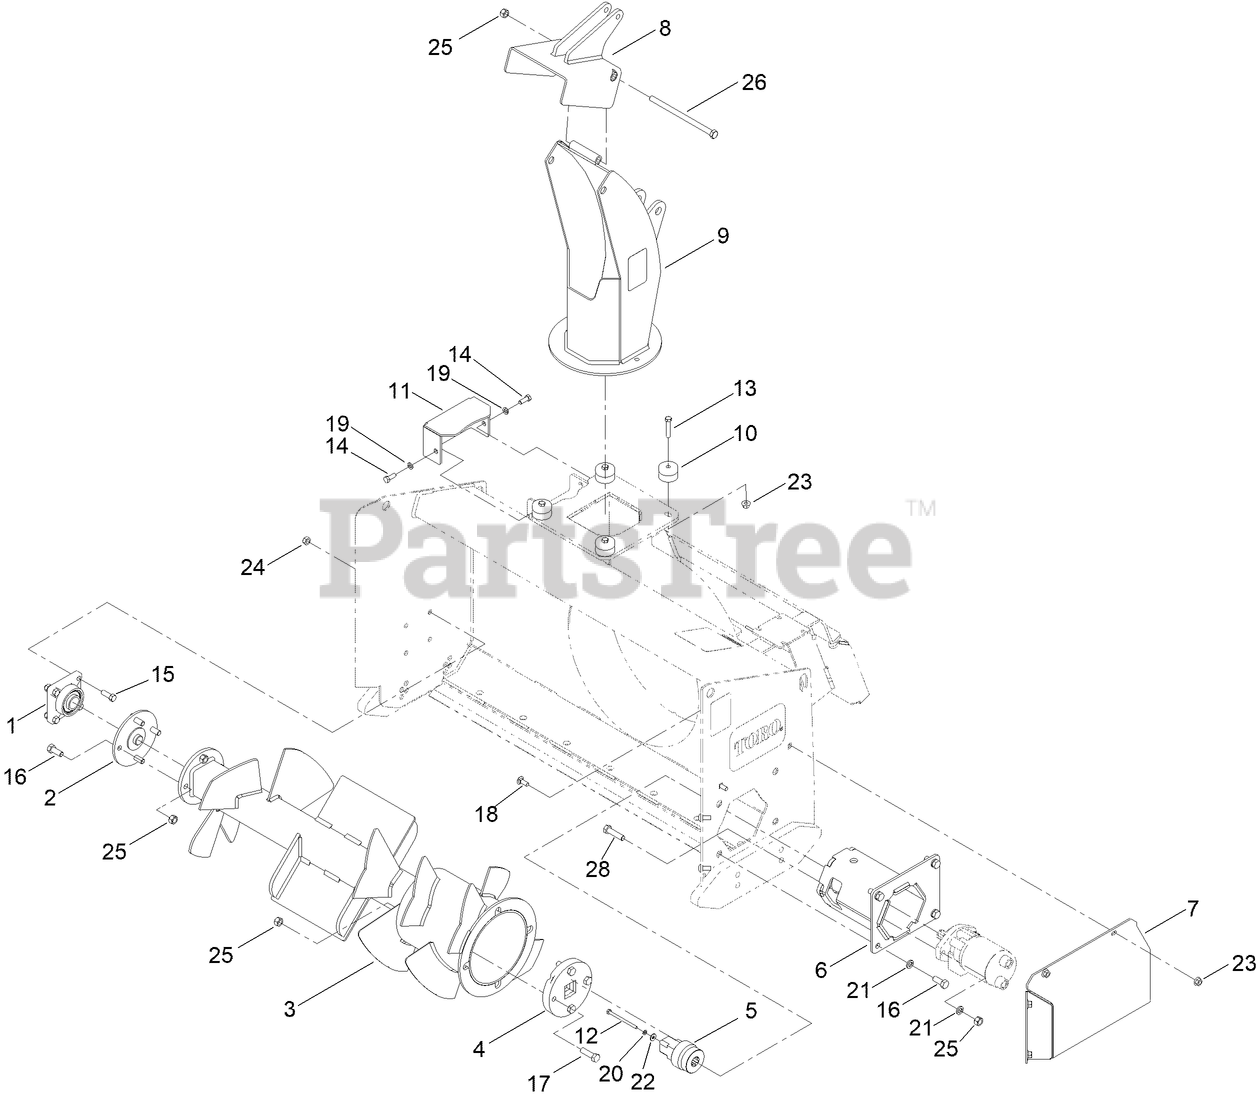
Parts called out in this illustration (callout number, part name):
1	BEARING
3	PADDLE ASM
4	COUPLER-PADDLE/MOTOR
5	ADAPTER- MOTOR
6	HOUSING-PADDLE MOTOR
7	HOUSING- HOSE PROTECTOR
8	DEFLECTOR
10	MOUNT-DEFLECTOR
11	COVER-CHUTE MOTOR SHAFT
12	SCREW-HH
13	SCREW-HH
14	SCREW-HH
15	SCREW-HH
16	SCREW-HH
17	SCREW-HH
18	BOLT-CARR
19	WASHER-LOCK
20	WASHER-LOCK
21	WASHER-LOCK
22	WASHER-FLAT
23	NUT-LOCK, FLANGE
24	NUT-HEX
25	NUT-HEX
26	SCREW-HH
28	SCREW-HH
